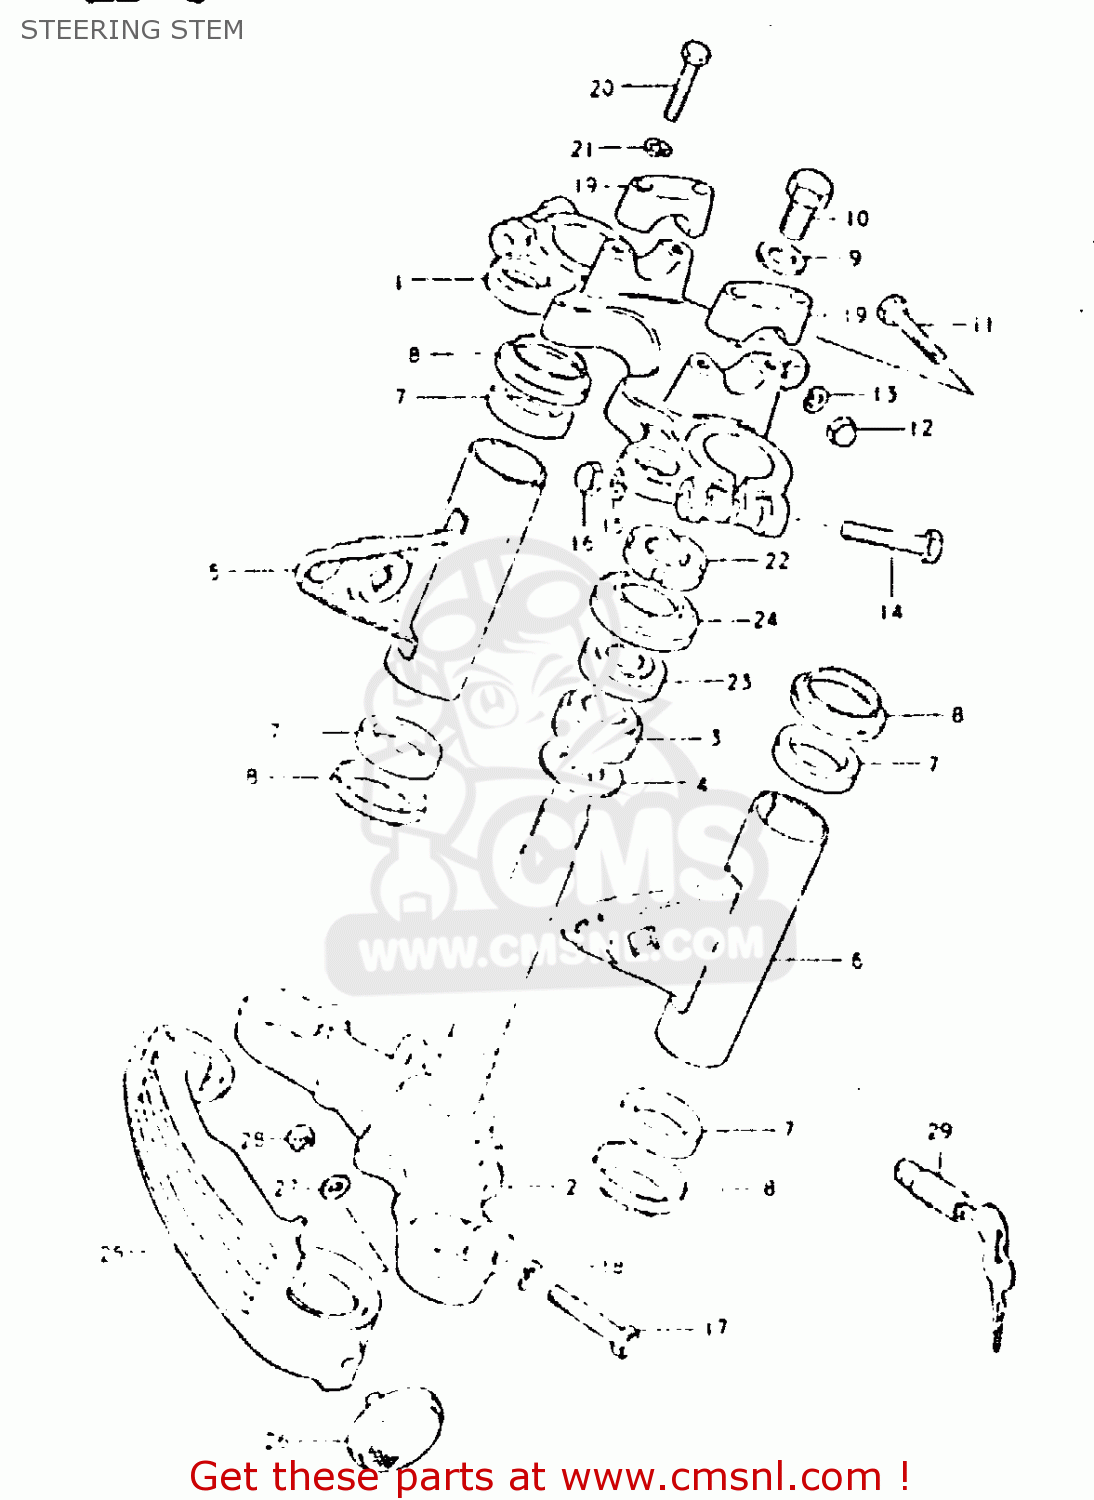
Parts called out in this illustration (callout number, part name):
1	HEAD,STEERING STEM
2	STEM,STEERING
3	BEARING
4	WASHER,THRUST
5	BRACKET,HEADLAMP,RIGHT
6	BRACKET,HEADLAMP,LEFT
7	CUSHION,HEADLAMP BRACKET
8	CAP,HEADLAMP BRACKET
9	WASHER
10	BOLT(12X20)
11	BOLT
12	NUT,M8X1.25X12
13	LOCK WASHER
14	BOLT
15	LOCK WASHER
16	NUT 10MM
17	BOLT 10X40
18	LOCK WASHER
19	HOLDER,HANDLE UPR
20	BOLT
21	LOCK WASHER
22	NUT,STEERING STEM(25X44X10)
23	TAPER,ROLLER BEARING
24	DUST SEAL,STEERING,UPPER
25	COVER,FRONT FORK
26	REFLEX REFLECTOR, FRONT
27	WASHER
28	NUT
